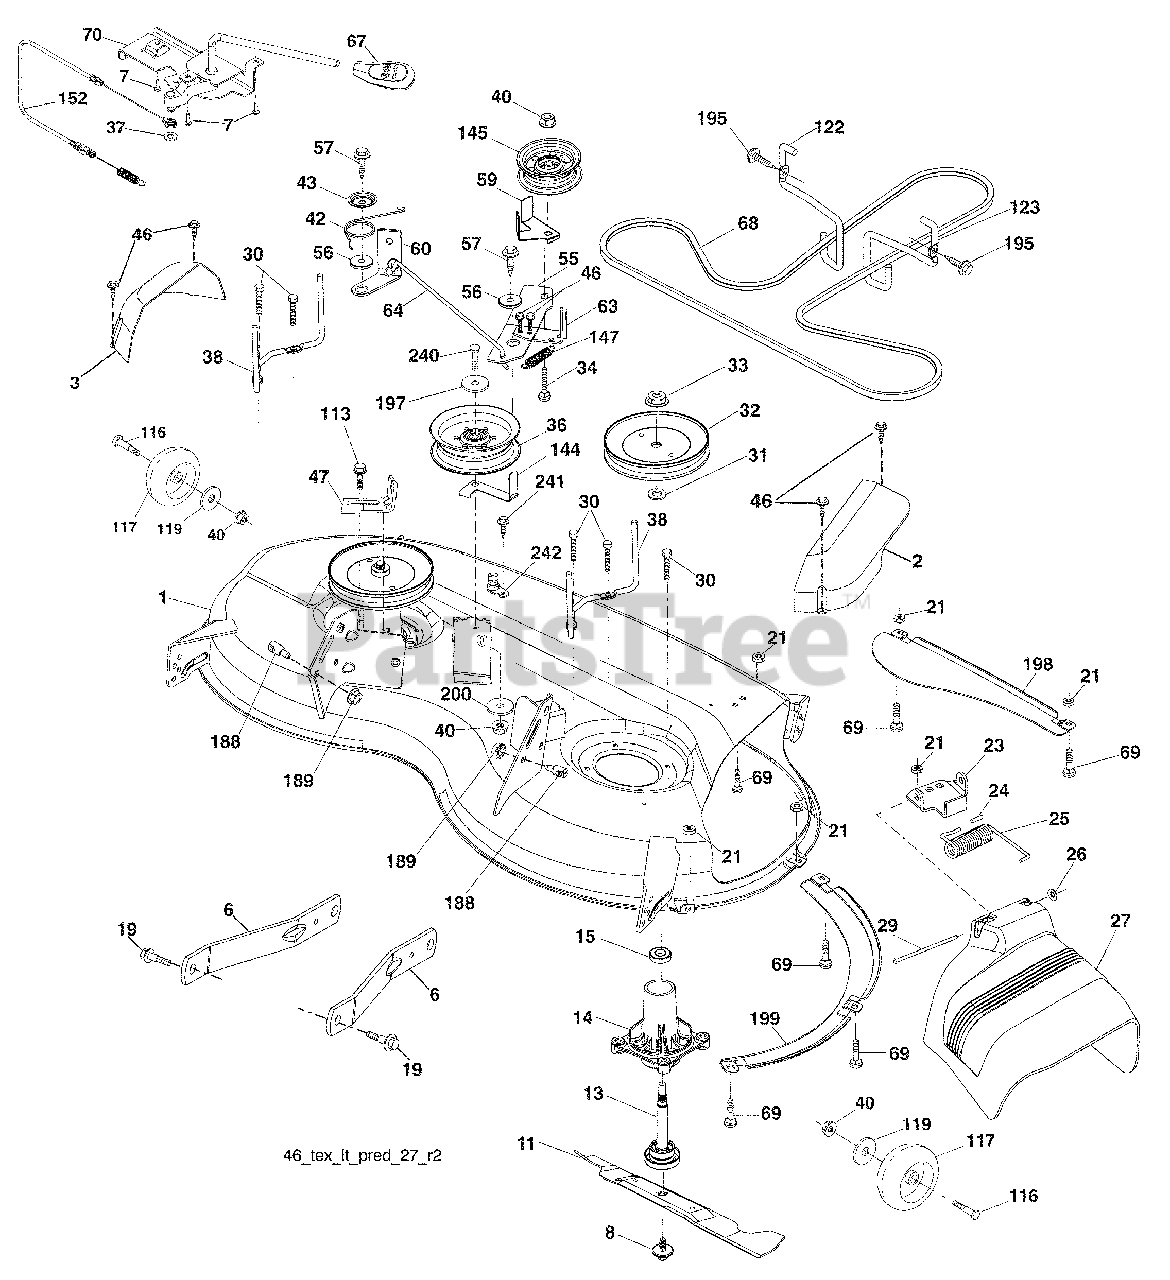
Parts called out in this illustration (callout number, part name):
1	Mower Housing
2	Cover Mandrel LH
3	Cover Mandrel RH
6	Arm Suspension
7	Screw # 10 x 0.750
8	Bolt/Washer asm 7/16-20 unf
11	Blade Mower Hi Lift
13	Shaft Assembly, Mandrel
14	Housing, Mandrel
15	Bearing, Ball, Mandrel
19	Bolt, Shoulder
21	Nut
23	Bracket, Deflector
24	Cap, Sleeve
25	Spring, Torsion, Deflector
27	Shield, Deflector
29	Rod, Hinge
30	Screw Thdrol Rolling Wsh Hd
31	Washer, Spacer
32	Pulley, Mandrel
33	Nut, Toplock, Flanged
34	Bolt Carr Sh. 3/8-16 x 1-1/2 Gr. 5
36	Pulley, Idler, Flat
37	Washer 13/32 x 13/16 x 16 Ga.
38	Keeper Belt LH Mandrel
40	Nut, Lock Flg. 3/8-16 unc
42	Spring Torsion Brake
43	Spring Torsion Retainer
47	Bracket Clutch Cable
55	Arm, Idler
56	Spacer, Retainer
57	Screw Hexwsh Thd 3/8-16 x 1
59	Guard, Tuv Idler (94)
60	Arm Brake Mower LH
63	Arm Brake Mower
64	Linkage Brake
67	Handle, Clutch Cable
68	V-Belt
69	Bolt
70	Clutch Asm. Cable
113	Screw 5/16-18
116	Bolt, Shoulder
117	Wheel, Gauge
119	Washer 13/32 x 1-1/4 x 12 Ga.
122	Keeper Belt Eng. LH
123	Keeper Belt Eng. RH
144	Keeper Belt
145	Pulley Idler
147	Spring Return
152	Cable Clutch Manual w/Spr.
188	Stud Fastener
189	Nut Lock Hex Flange
195	Screw 3/8-16 x 3/4
197	Washer 13/32 x 13/16 x 12 Ga.
198	Baffle Center Front
199	Baffle Front RH
200	Washer 13/32 x 1 x 1/2 11 Ga.
240	Bolt 3/8-16 unc x 2-1/4 Gr. 5
242	Washout Port
